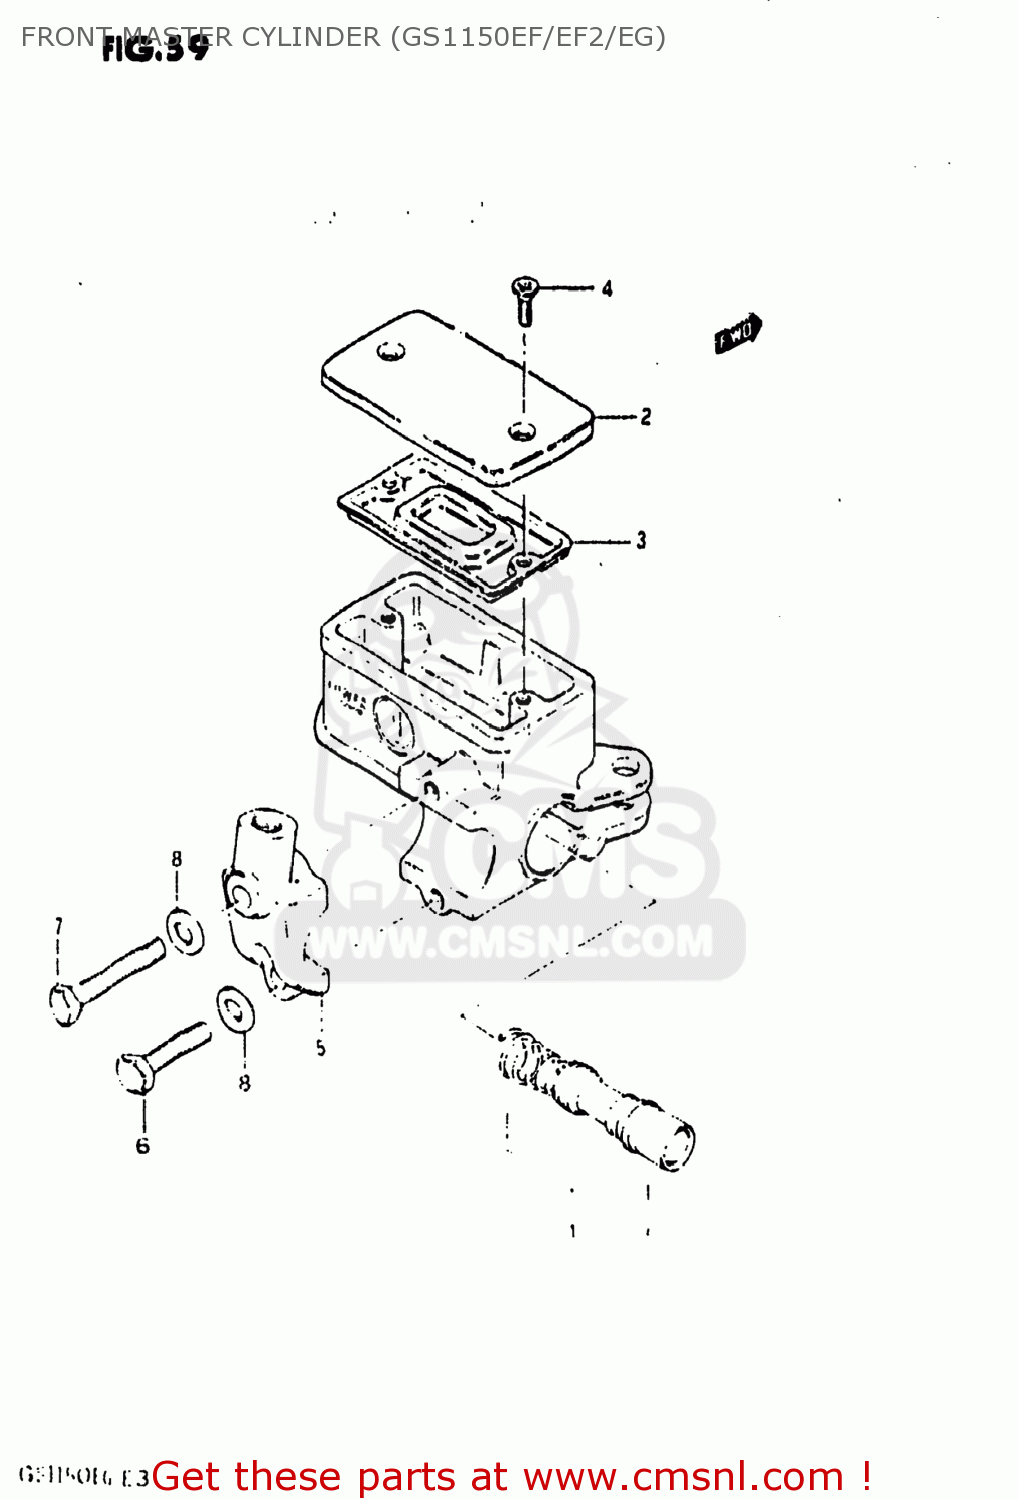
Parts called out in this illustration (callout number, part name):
1	PISTON & CUP SET
2	CAP
3	4
4	SCREW
5	HOLDER
6	BOLT
7	BOLT
8	WASHER
